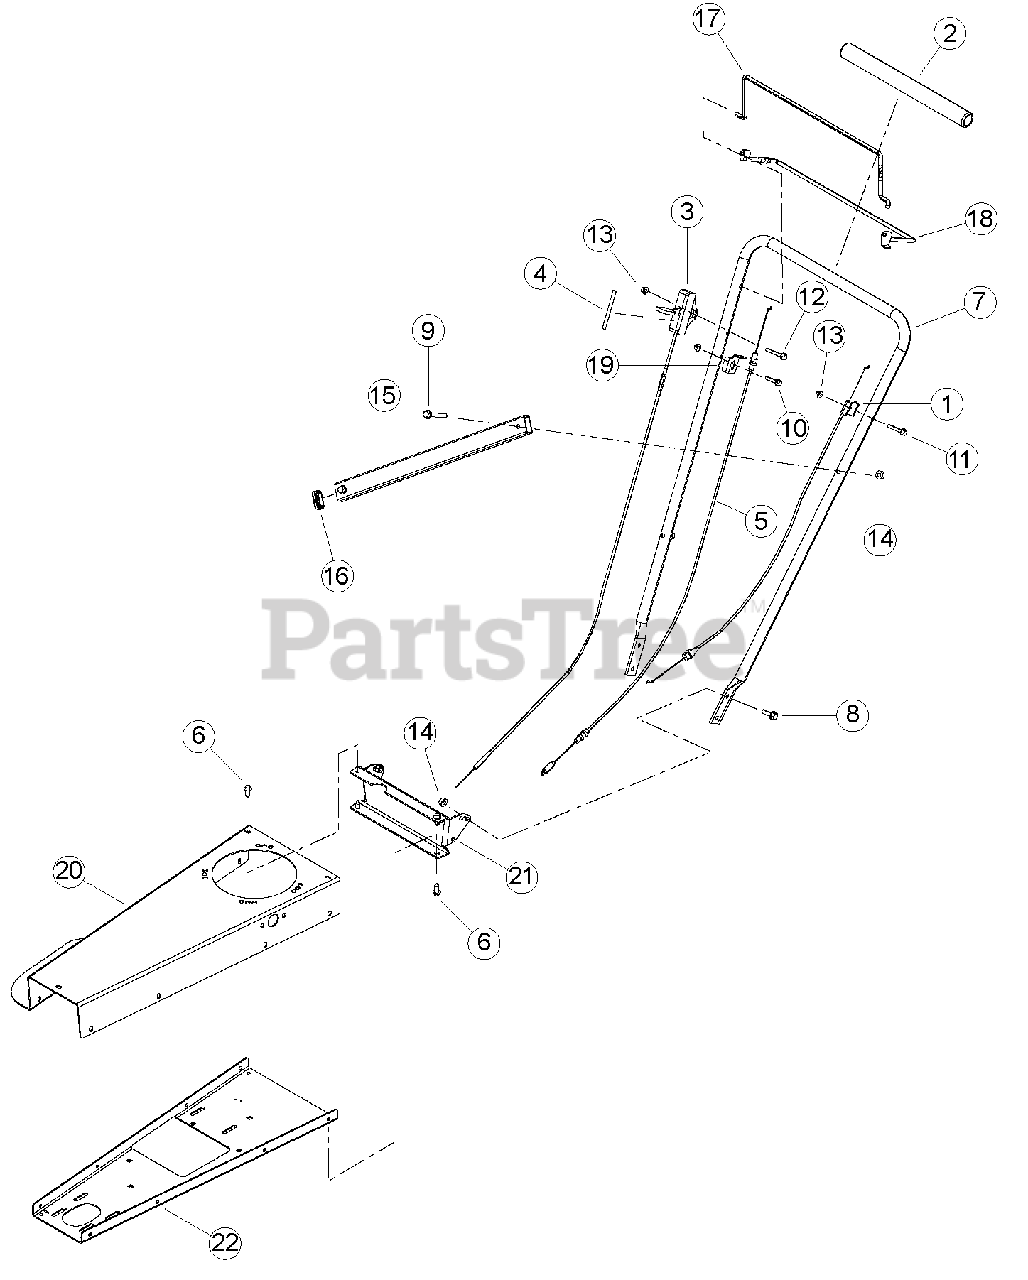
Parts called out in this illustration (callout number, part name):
1	CABLE, BRAKE CONTROL
2	PAD, FOAM HANDLEBAR
3	CABLE, TRANSMISSION CONTROL
4	DECAL, 3 SPEED
5	CABLE, SP CONTROL
6	SCREW, 11/32 X 7/8 HWH AB THREAD ZP
7	HANDLEBAR, TRIMMER
8	BOLT, 5/16 X 1 FLANGE NC
9	BOLT, 5/16 X 2-1/4 FLANGE NC
10	BOLT, 1/4 X 1-1/4 FLANGE NC
11	BOLT, 1/4 X 1-1/2 FLANGE NC
12	BOLT, 1/4 X 1-3/4 FLANGE NC
13	NUT, 1/4-20 NYLOCK-FLANGE
14	NUT, 5/16-18 NYLOCK-FLANGE
15	ASSEMBLY, WT LINE HOLDER
16	CAP, PLASTIC 3/4 X 1-1/2 TUBE
17	BAIL, TRIMMER
18	WELDMENT, SP BAIL
19	ANCHOR, SP CABLE
20	BODY, TRIMMER
21	CHANNEL, HANDLE SUPPORT
22	BOTTOM, TRIMMER FRAME
